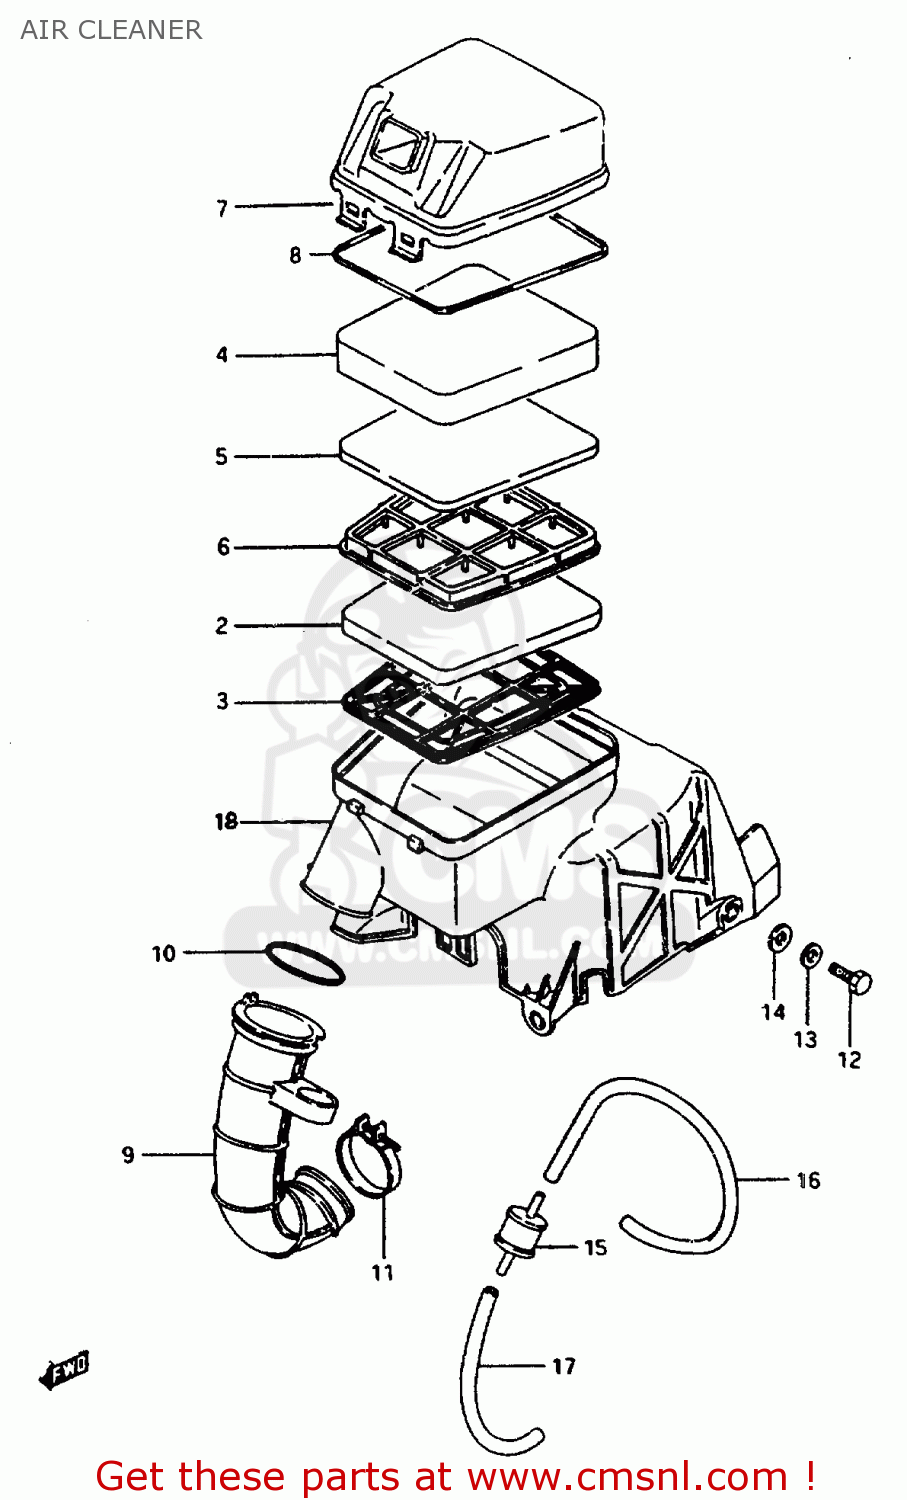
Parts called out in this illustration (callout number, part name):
2	FILTER,AIR
3	HOLDER,AIR CLE
4	PREFILTER(A)
5	PREFILTER(B)
6	HOLDER,UPPER
7	CAP,AIR CLEANE
8	GASKET (3*5*400)
9	TUBE,AIR CLEANER OUTLET
10	CLAMP
11	CLAMP
12	BOLT 6X16
13	LOCK WASHER
14	WASHER B6 DIN 125
15	VALVE, VACUUM TRANSMITTING
16	HOSE (3.5*6.5*220)
17	HOSE (3.5*6.5*220)
18	CASE COMP, AIR CLANER
